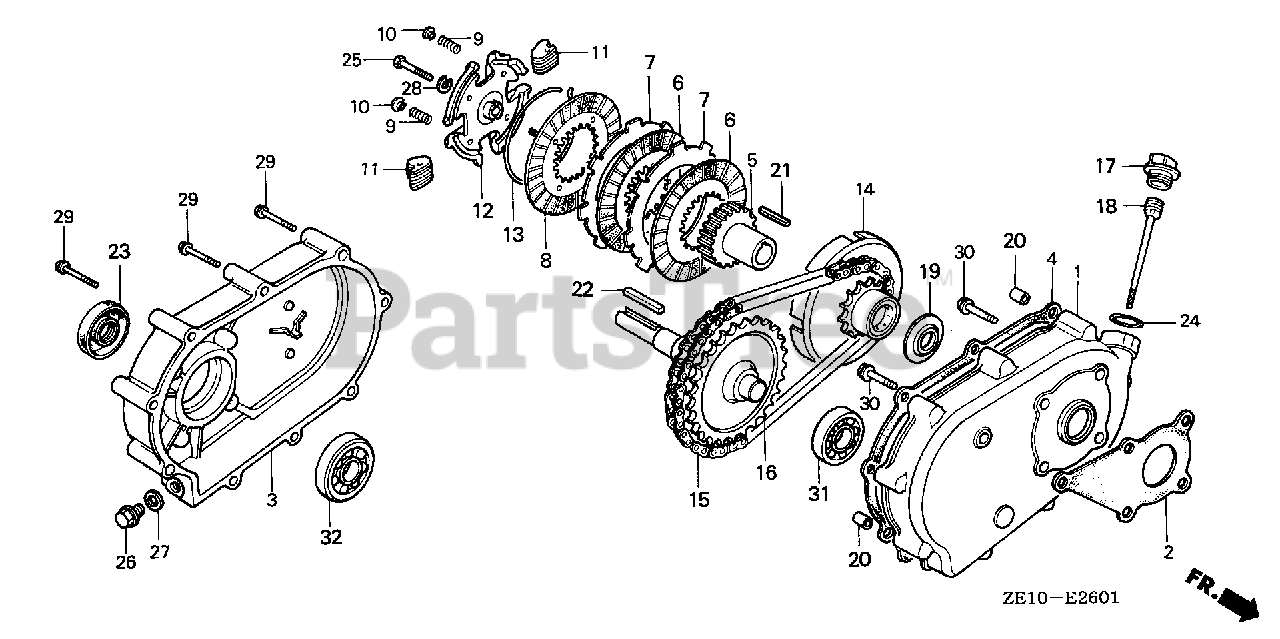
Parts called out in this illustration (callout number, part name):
1	CASE, REDUCTION
2	GASKET, REDUCTION CASE
3	COVER, REDUCTION
4	GASKET, REDUCTION COVER
4	GASKET, REDUCTION
5	CENTER, CLUTCH
6	DISK, CLUTCH FRICTION
7	PLATE, CLUTCH
8	PLATE, CLUTCH PRESSURE
9	SPRING, CLUTCH FREE
10	HOLDER, CLUTCH SPRING
11	WEIGHT, CLUTCH
12	HOLDER, CLUTCH WEIGHT
13	CENTER, CLUTCH WEIGHT
14	SPROCKET, DRIVE
15	CHAIN, DRIVE (RK428SH-36LE)
16	SHAFT, P.T.O. (28T)
17	CAP, REDUCTION OIL (GRAY)
18	DIPSTICK, OIL
19	WASHER, THRUST (20MM)
20	PIN, DOWEL (8X10)
22	KEY (7X7X33) (YELLOW)(O/S)
23	OIL SEAL (PJ30507)
24	O-RING (26X2.7)
25	BOLT, HEX. (8X35)
26	BOLT, DRAIN PLUG (12MM)
27	WASHER, DRAIN PLUG (12MM)
28	WASHER, SPRING (8MM)
29	BOLT, FLANGE (6X55)
30	BOLT, FLANGE (8X22)
31	BEARING, RADIAL BALL (6205)
32	BEARING, RADIAL BALL (6206)
